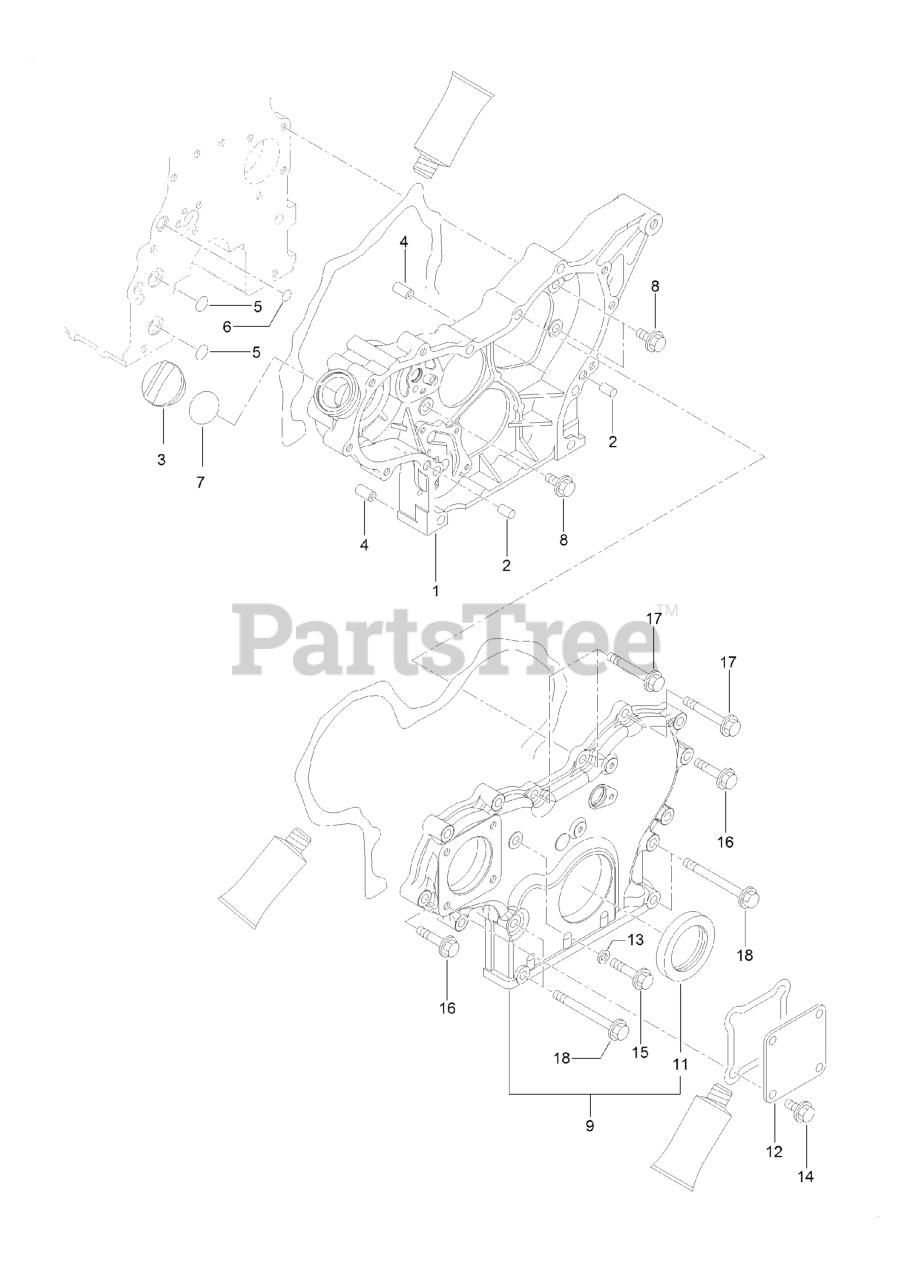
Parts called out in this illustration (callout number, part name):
1	Case-Gear
3	COVER-FILLER
8	BOLT
9	GEARCASE COVER ASM
11	SEAL-OIL
13	WASHER-SEAL
14	BOLT
